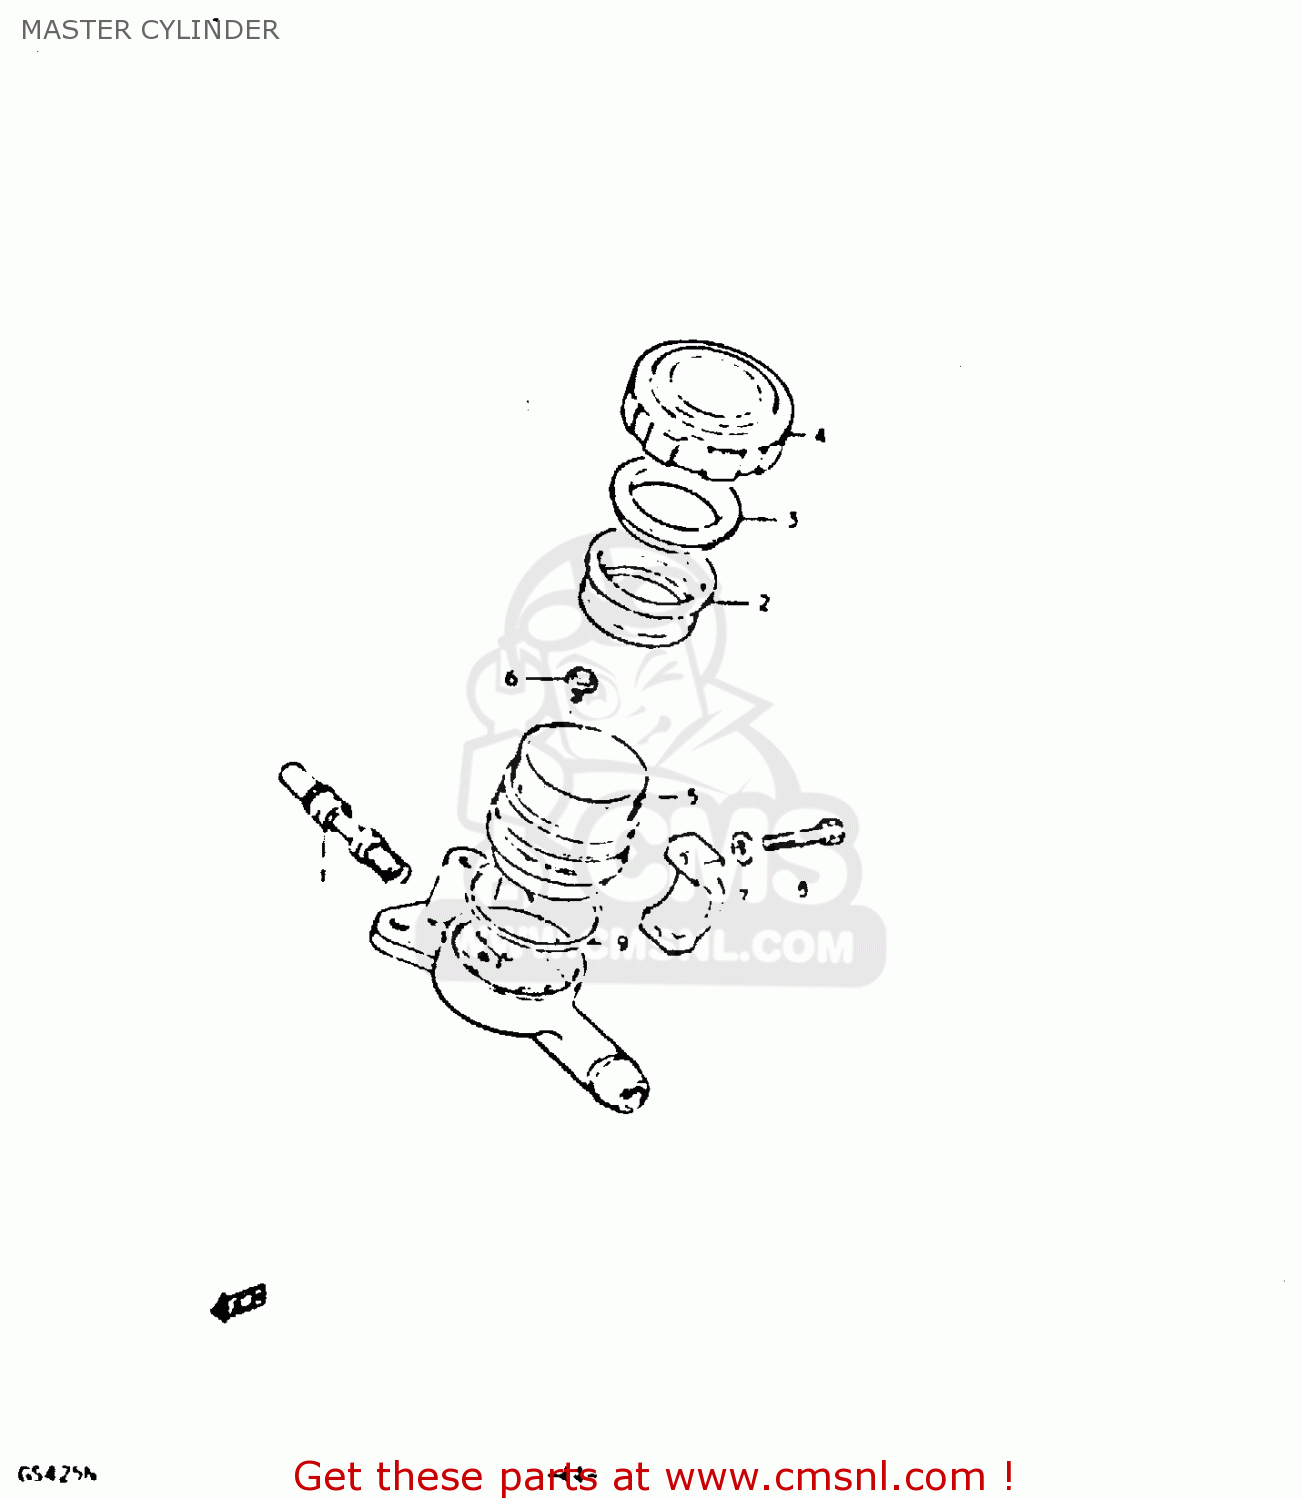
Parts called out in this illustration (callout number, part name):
1	CYLINDER ASSEMBLY,FRONT MASTER
2	DIAPHRAGM
3	PLATE,DIAPHRAGM
4	CAP
5	RESERVOIR
6	SCREW,MASTER CYLINDER
7	WASHER
8	BOLT
9	O RING
